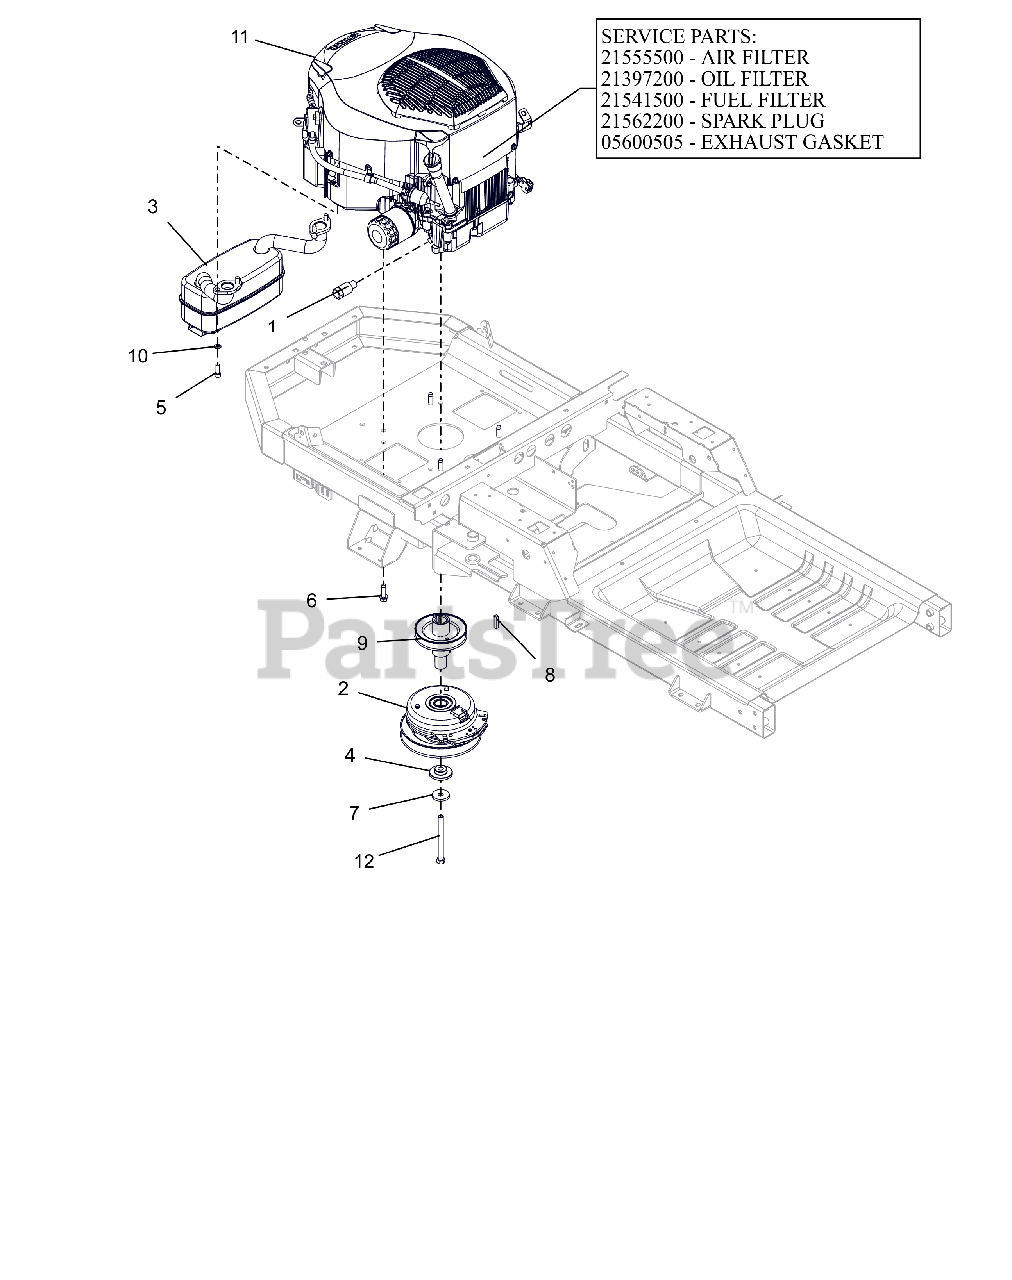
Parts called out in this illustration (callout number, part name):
1	DRAIN, OIL
2	CLUTCH,105FTLB MONOPOLE 6.83"
3	MUFFLER - KOHLER
4	BSHG-FLG .469X1.06X.574X2.0
5	SCR-CAP .31-18X.88 S/HD G8 ZCC
6	SCR,TAP .375-16X1.25HWH TR ZCC
7	WASHER, 7/16" SPRING DISK
8	KEY-SQ .25 X 1.25 X .25 SAE
9	WLDMT, DRIVE SHEAVE-X
10	WSHR,LK-REG .312X.078 ZCC
11	ENGINE, KOHLER 22HP TWIN
11	AIR CLEANER, KOHLER
11	FILTER, OIL - KOH CV20
11	FILTER, FUEL
11	PLUG, SPARK (RFI)
11	GASKET, MUFFLER COURAGE TWIN
12	BLT, HEX .44-20X4.50 G8 ZCC NT
